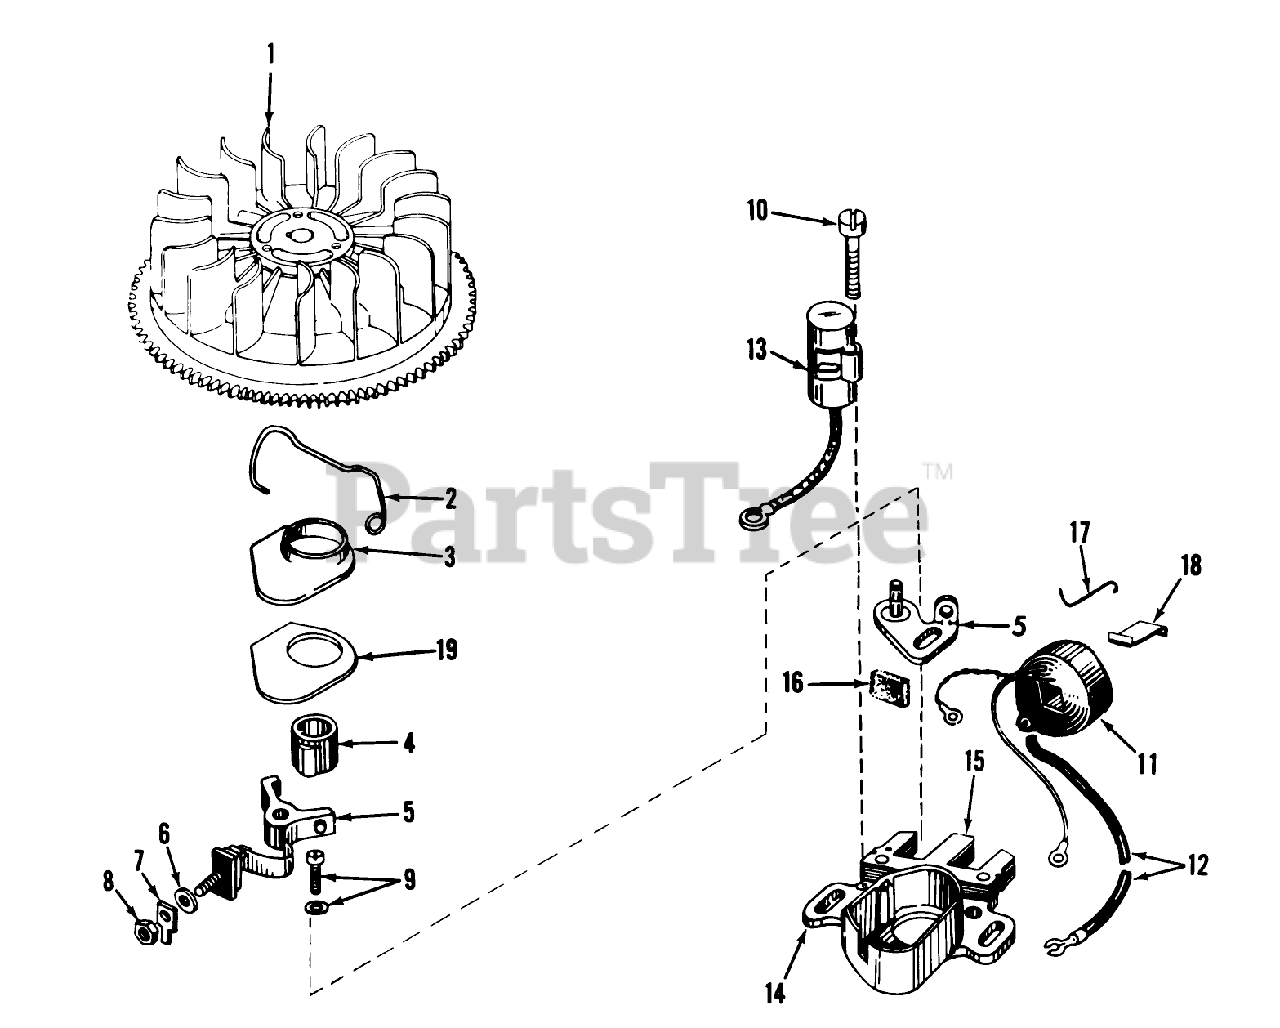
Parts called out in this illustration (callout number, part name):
1	Flywheel
2	Spring Breaker Box
3	Cover, Dust
4	Cam-Breaker
5	Breaker Assy.
6	Washer
7	Terminal
8	DECAL
9	Breaker Screw
10	Condenser Screw
11	Coil Assy., (Inc. Ref. Nos. 12, 13 18)
12	Wire, Lead
13	Condenser
14	Core Plate
15	Stator Assy., (Incl. Nos. 2, 3, 5 thru 14 16 thru 19)
16	Felt,Cam Wiper
17	Clip, Coil
18	Spring Coil Wedge
19	Gasket Dust
